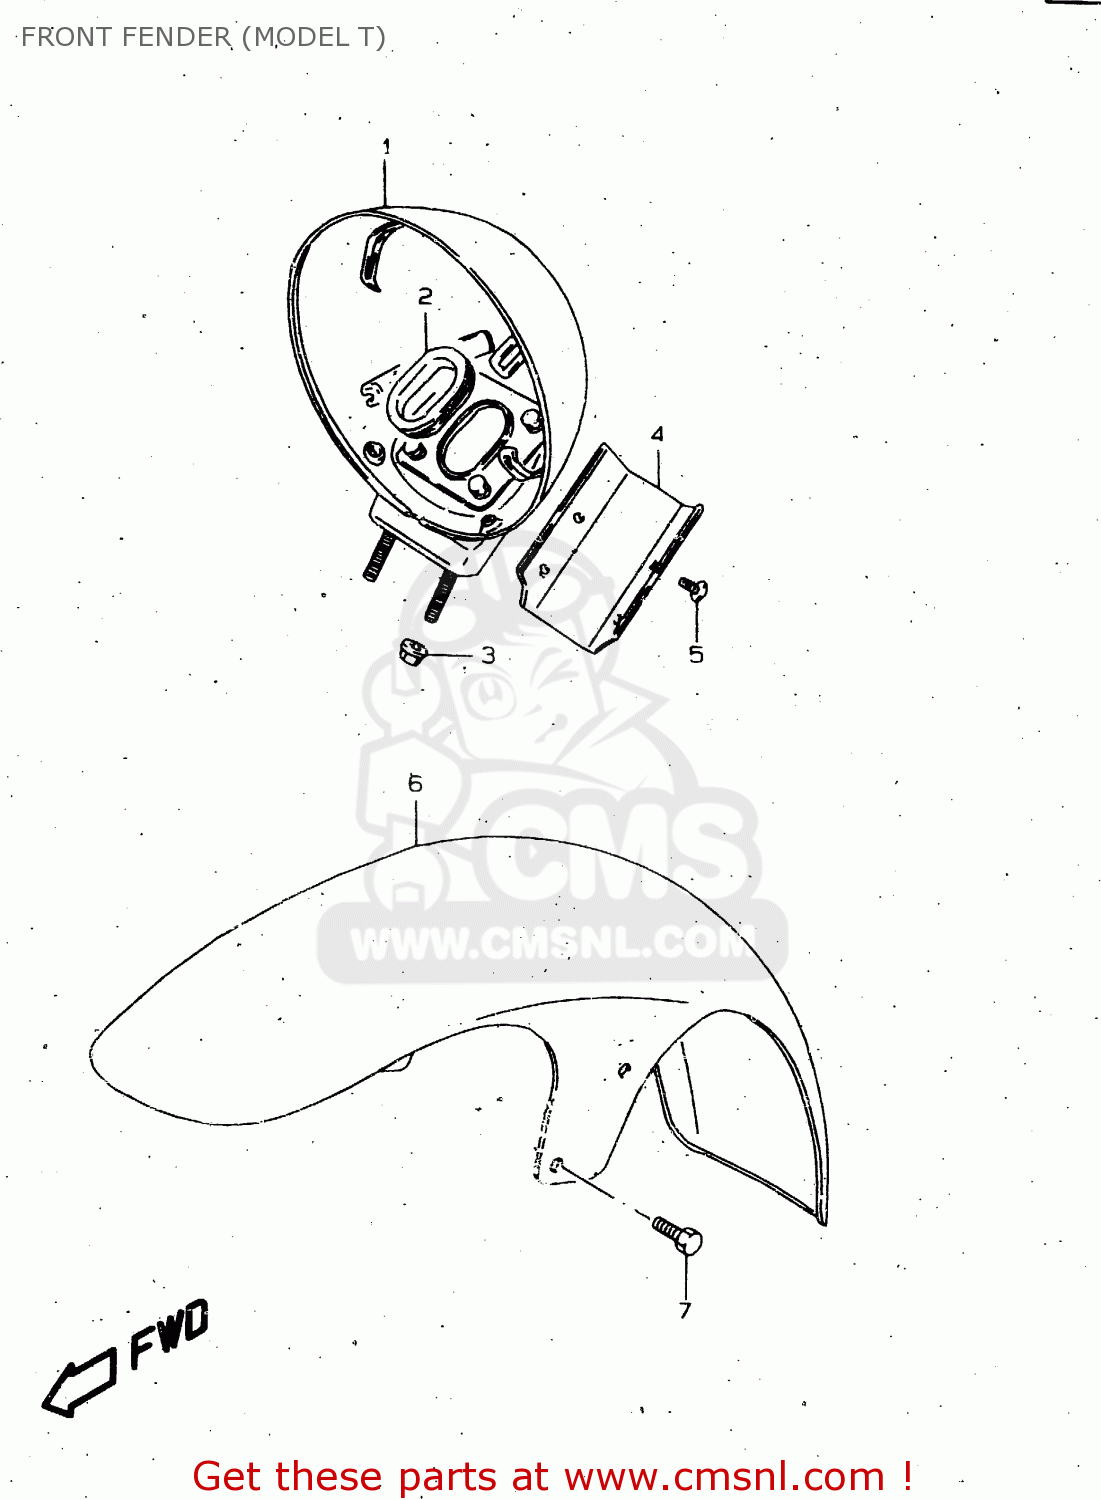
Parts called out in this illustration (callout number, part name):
1	HOUSING,HEADLAMP
2	GROMMET
3	NUT
4	COVER,HEADLAMP HSG
5	SCREW
6	FENDER COMP,FRONT
7	BOLT
